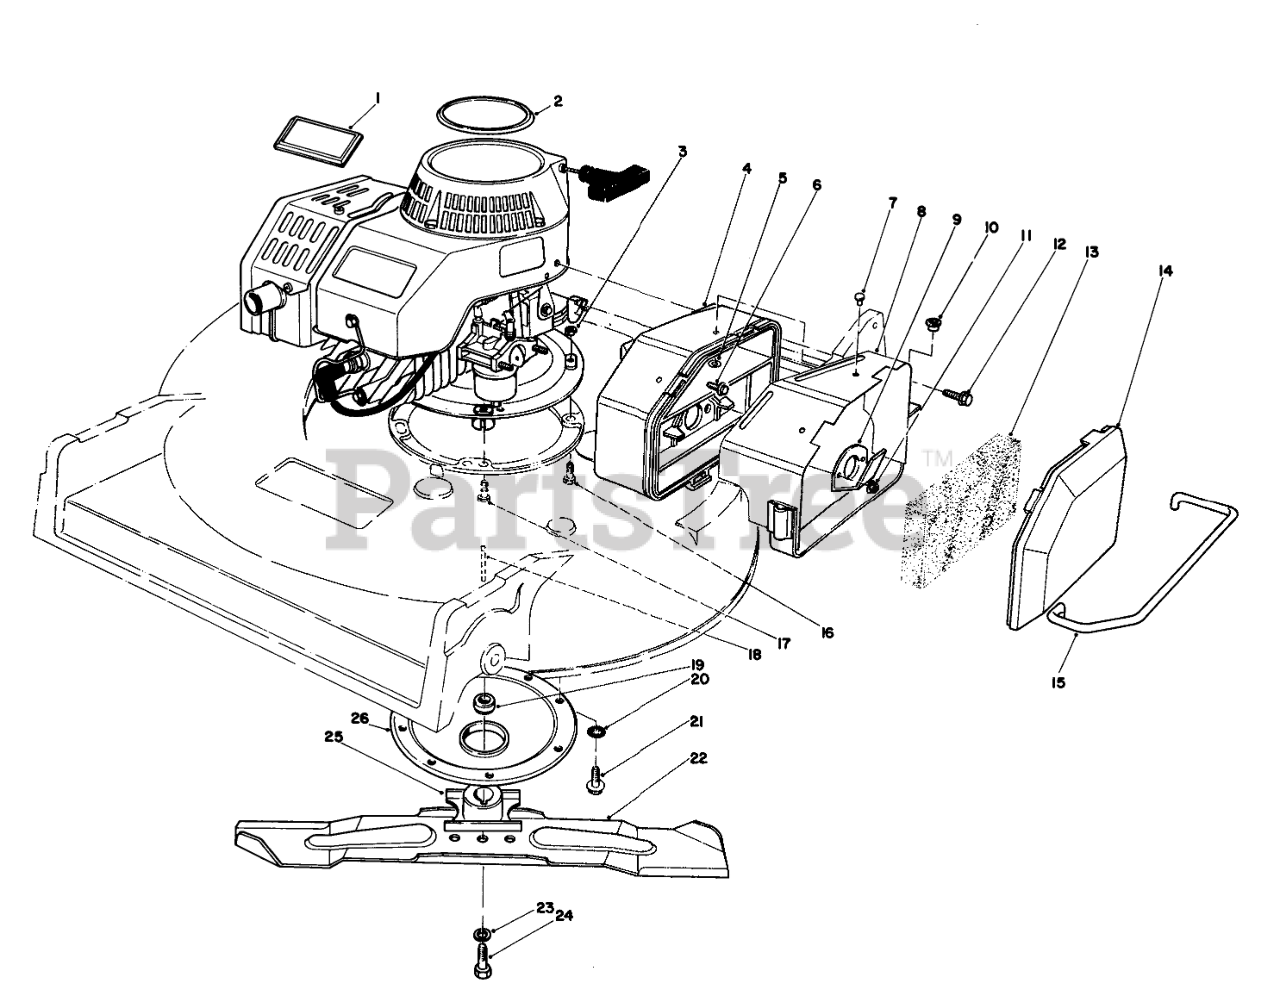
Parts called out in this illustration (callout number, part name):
1	Plate-Logo
2	Plate-Engine Logo
3	NUT-JAM
4	Air Cleaner Assembly (Incl. Ref. #5,7,8)
5	WASHER-FLAT
6	HEX FL HD M.6X1.0X25MM
7	RIVET-POP
8	AIR CLEANER COVER WA
9	SPIT BACK DEFLECTOR
10	5/16 ID BSHG
11	NUT-LOCK
12	SCREW-HHF
13	FILTER
14	AIR CLEANER COVER
15	AIR CLEANER GUARD
16	SCREW-HH
17	SCREW-HH
18	KEY-SQUARE
19	SPACER-BLADE RETAINER
20	WASHER-LOCK, INTERNAL
21	Screw-Self Tapping
22	BLADE-21in
23	WASHER-LOCK
24	SCREW-BLADE
25	RETAINER-BLADE
26	PROTECTOR-CRANKSHAFT
